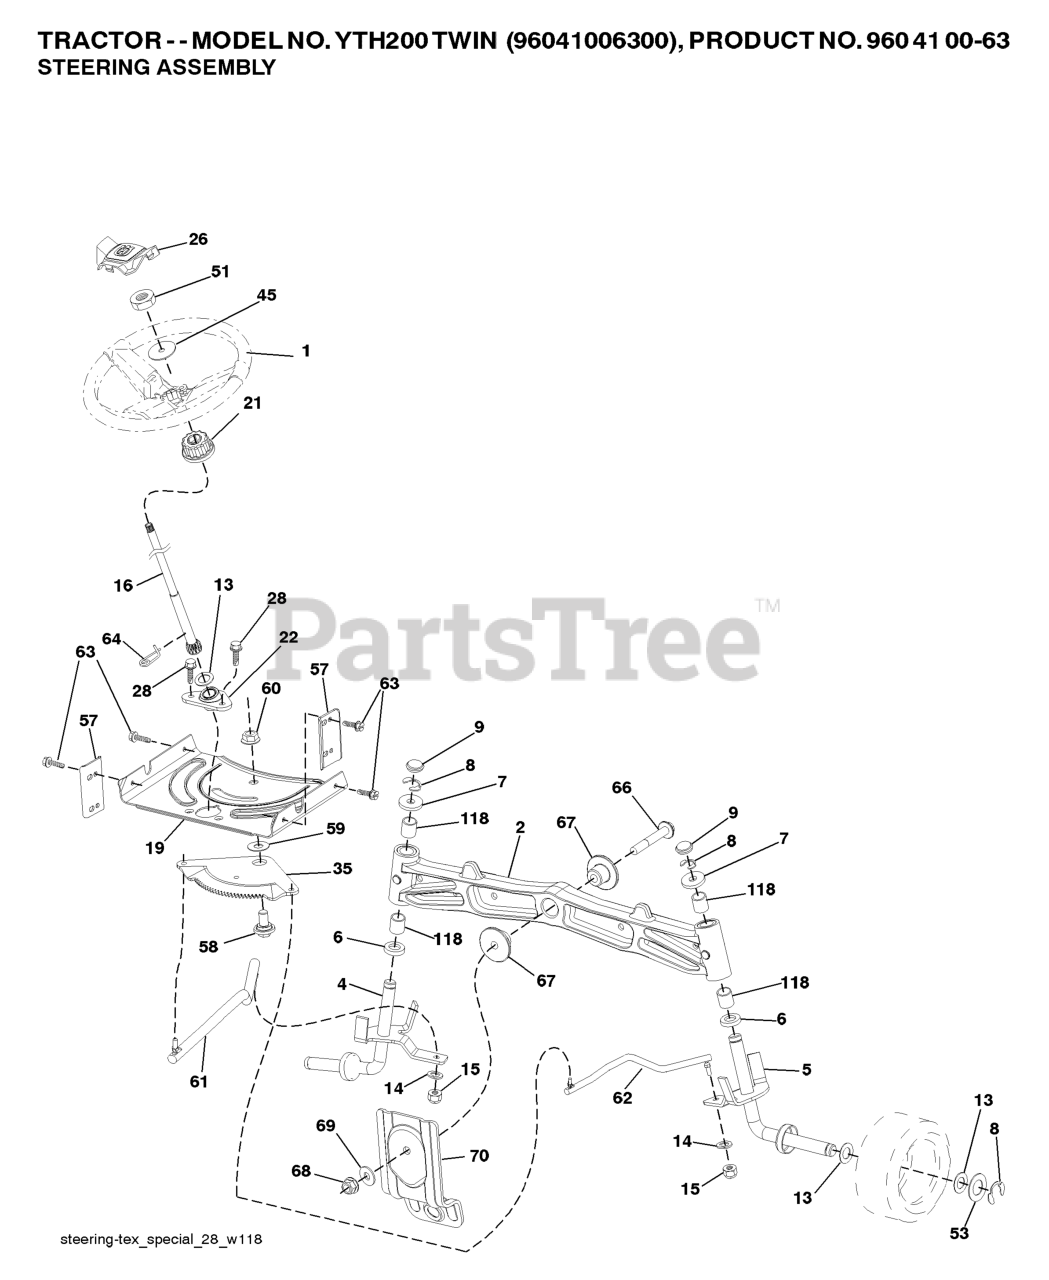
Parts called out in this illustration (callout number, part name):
1	RP WHEEL.STEER.HUSQ.PREM.OVMLD
2	AXLE ASSY FRONT
4	SPINDLE.WELDED.LH.15"TEX
5	SPINDLE.WELDED.RH.15"T
6	THRUST WASHER
9	CAP.SPINDLE.BLACK
14	WASHER, LOCK 3/8
15	NUT CROWNLOCK 3/8-24
16	SHAFT.STEER.STEALTH.DD
19	PLATE.STEER.DDL.NLT/NG
21	ADAPTER, WHEEL STNG..
22	BUSHING.ASM.STEERING.A
26	RP INSERT.CAP.WHL.STRG.HUSQ.
28	SCREW, 3/8-16X3/4
35	GEAR.SECTOR.PLATE.DDL.
45	WASHER 9/16"ID, 2 3/8"OD
51	NUT.HEX.1/2-20
53	WASHER.HARDENED
57	BRACKET.UPSTOP.TEX
58	BOLT.SHOULDER.SECTOR.P
59	WASHER.THURST.SECTOR.S
60	NUT FLANGE LOCK 5/8-11
61	DRAGLINK.LH.BALLSTUD.D
62	DRAGLINK.RH.BALLSTUD.D
63	SCREW
64	RETAINER.CLIP.SPRING.S
66	BOLT HEX FGHD 7/16-14 X 3 SERR
67	BUSHING.PM.FRONT AXLE
68	NUT.LOCK.FLANGE.7/16
69	WASHER.1.5X.505X.118
70	BRKT.DECK.SUSPENSION.F
79	DECAL.WHEEL.STRG.LGN.H
118	BUSHING, AXLE CAST
